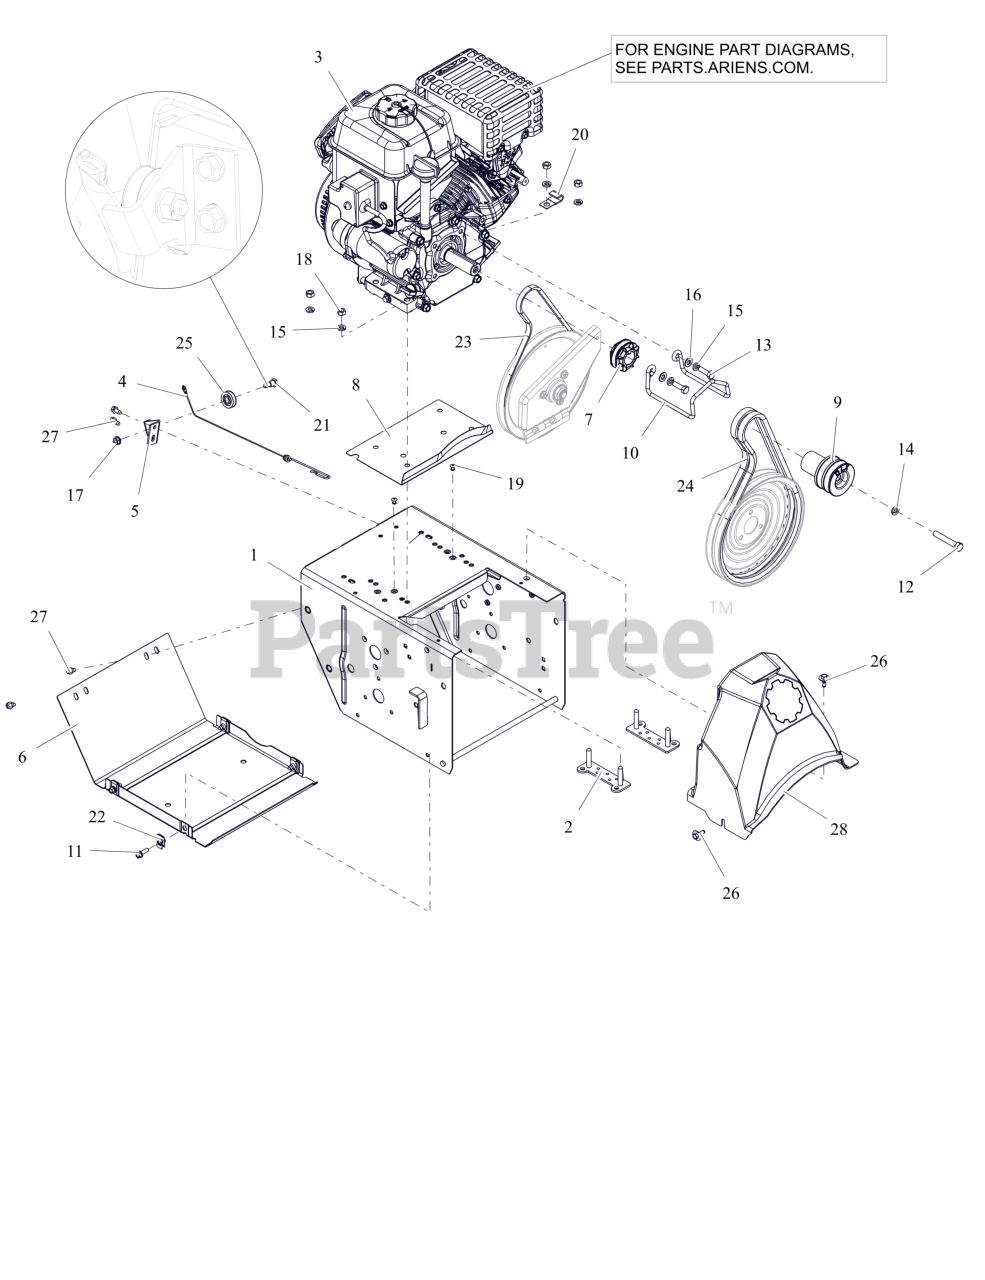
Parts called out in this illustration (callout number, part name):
1	FRAME, MAIN - 14GA DELUXE (ORANGE)
2	STRAP, BOLT - SMALL ENGINE
3	Engine, AX 254 OPP 120V/60W
4	CABLE, LOWER TRACTION,SS & PRO
5	BRACKET, CABLE PULLEY
6	COVER, BOTTOM
7	SHEAVE, DRIVE
8	BAFFLE, WATER-SMALL
9	SHEAVE, ATTACHMENT - STANDARD 2 GRV
10	FINGER, BELT
11	BLT, HWH .25-20X.75 G5 ZCC
12	BLT, HEX .38-24X2.25 G5 ZCC
13	BLT, HEX 0.3125-24X1 G5 ZCC
14	WSHR,LK-REG .375X.094 ZCC
15	WSHR, LK-HVY .312X.097 ZCC
16	WSHR,FLT .344X.688X.065 ZCC
17	NUT-LK-TOP-FLG .250-20 GF ZCC
18	NUT, HEX .312-18 ZCC
19	RVT, POP .1875 ZCC
20	J-CLAMP
21	BOLT, SHLDR -.375 X .375 X .25-20
22	NUT-RTNR .25-20X.56
23	V-BELT, 3L-WRAPPED
24	V-BELT, HA-RAW EDGE (SET)
25	PULLEY, CABLE
26	SCR-TAP .25-20X.5 CAPTIVE
27	SCR-TAP .25-20X.50 HWH ZCC
28	COVER, BELT - SMALL
